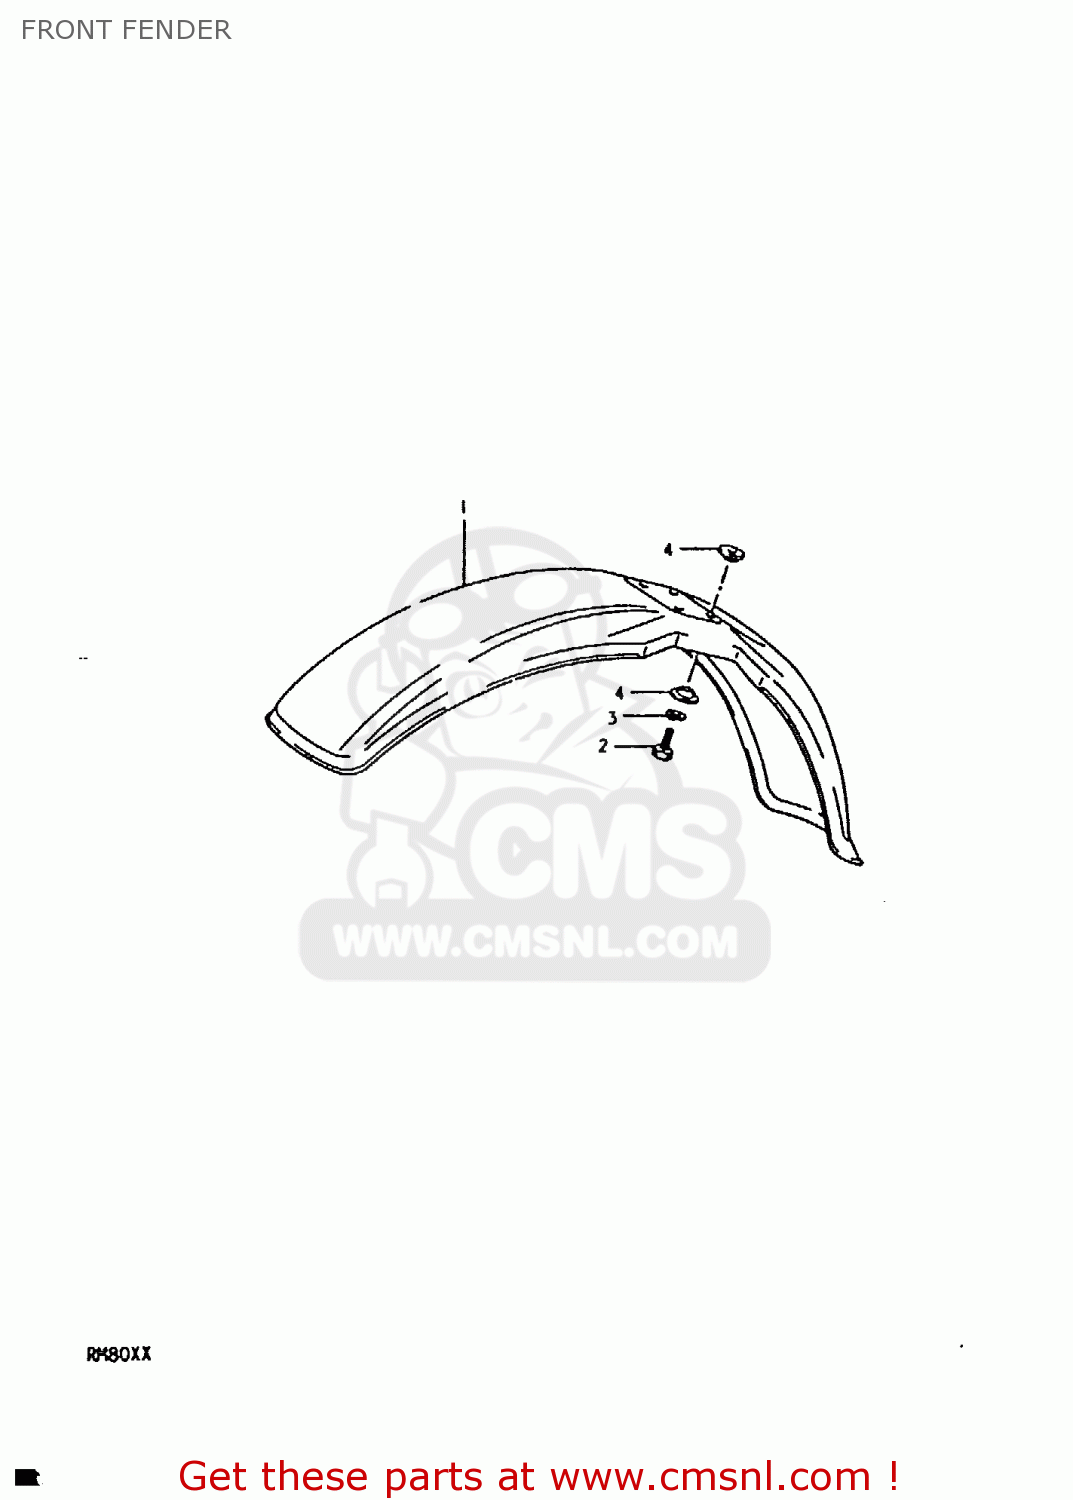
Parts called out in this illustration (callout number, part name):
1	FENDER,FRONT
2	BOLT, UPPER
3	LOCK WASHER
4	SPACER
